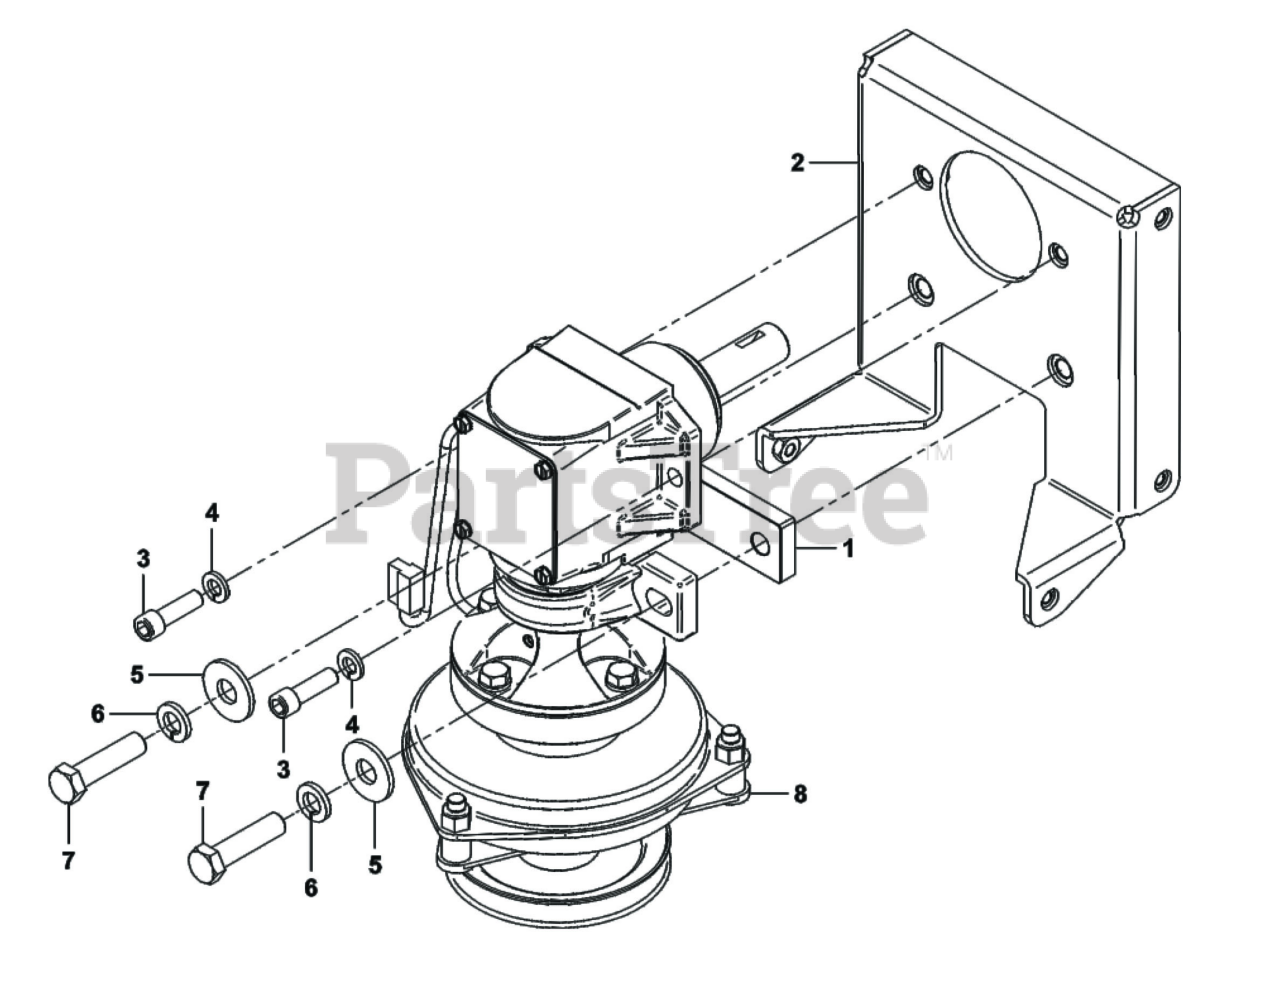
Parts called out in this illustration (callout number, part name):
1	SPACER PLATE
2	DRIVE MOUNT ASSEMBLY
3	SCREW 3/8"-16 X 1.25"
4	LOCK WASHER 3/8
5	FLAT WASHER 1/2"
6	LOCK WASHER 1/2"
7	SCREW 1/2"-13 X 2"
